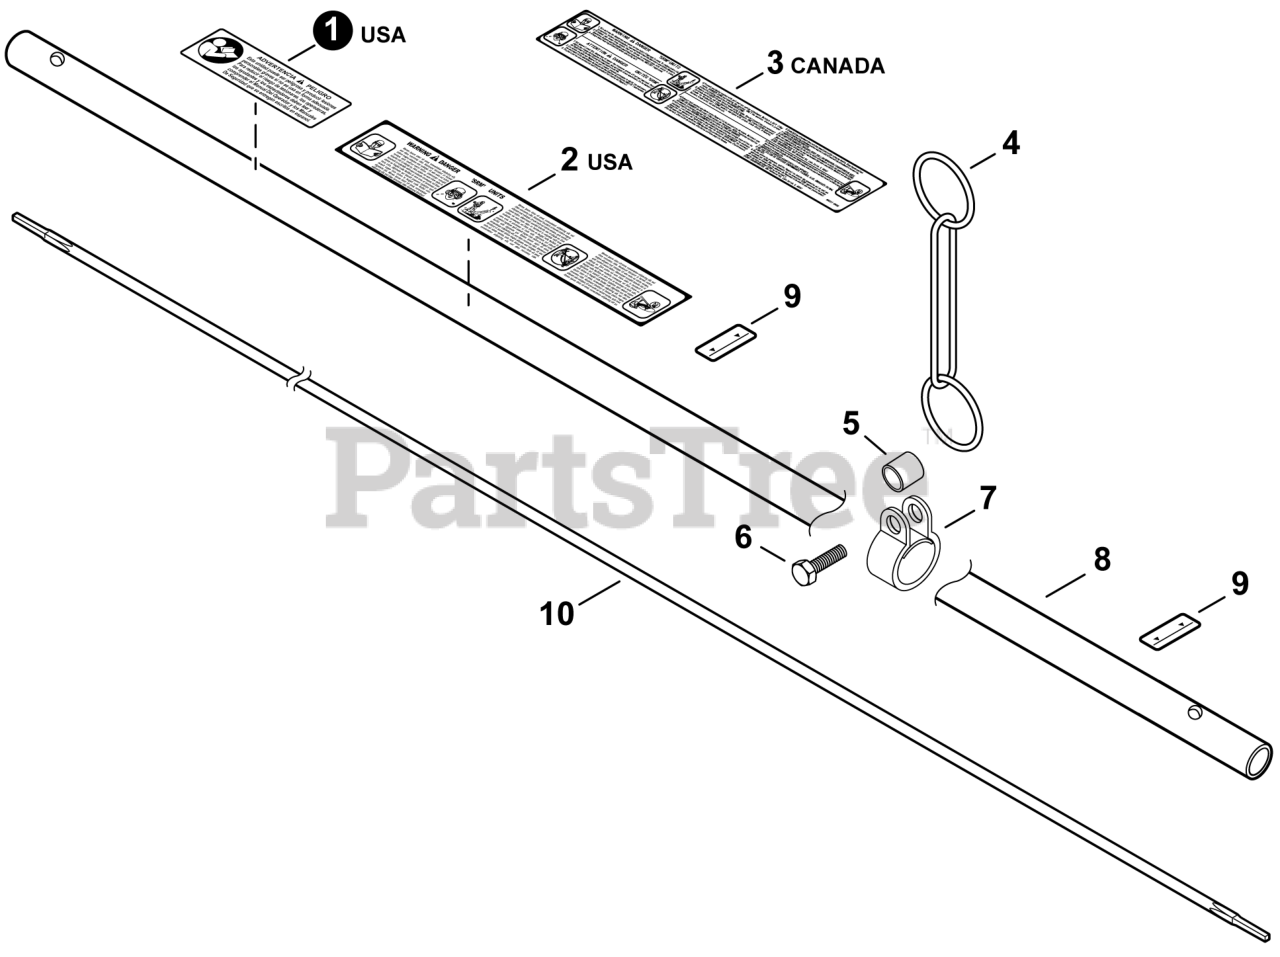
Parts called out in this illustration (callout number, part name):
1	LABEL - CAUTION
2	LABEL - CAUTION
3	LABEL - CAUTION
4	RING, HARNESS
6	BOLT, FLANGE
7	HANGER, HARNESS
8	PIPE, MAIN
9	LABEL - ALIGNMENT
10	DRIVESHAFT
